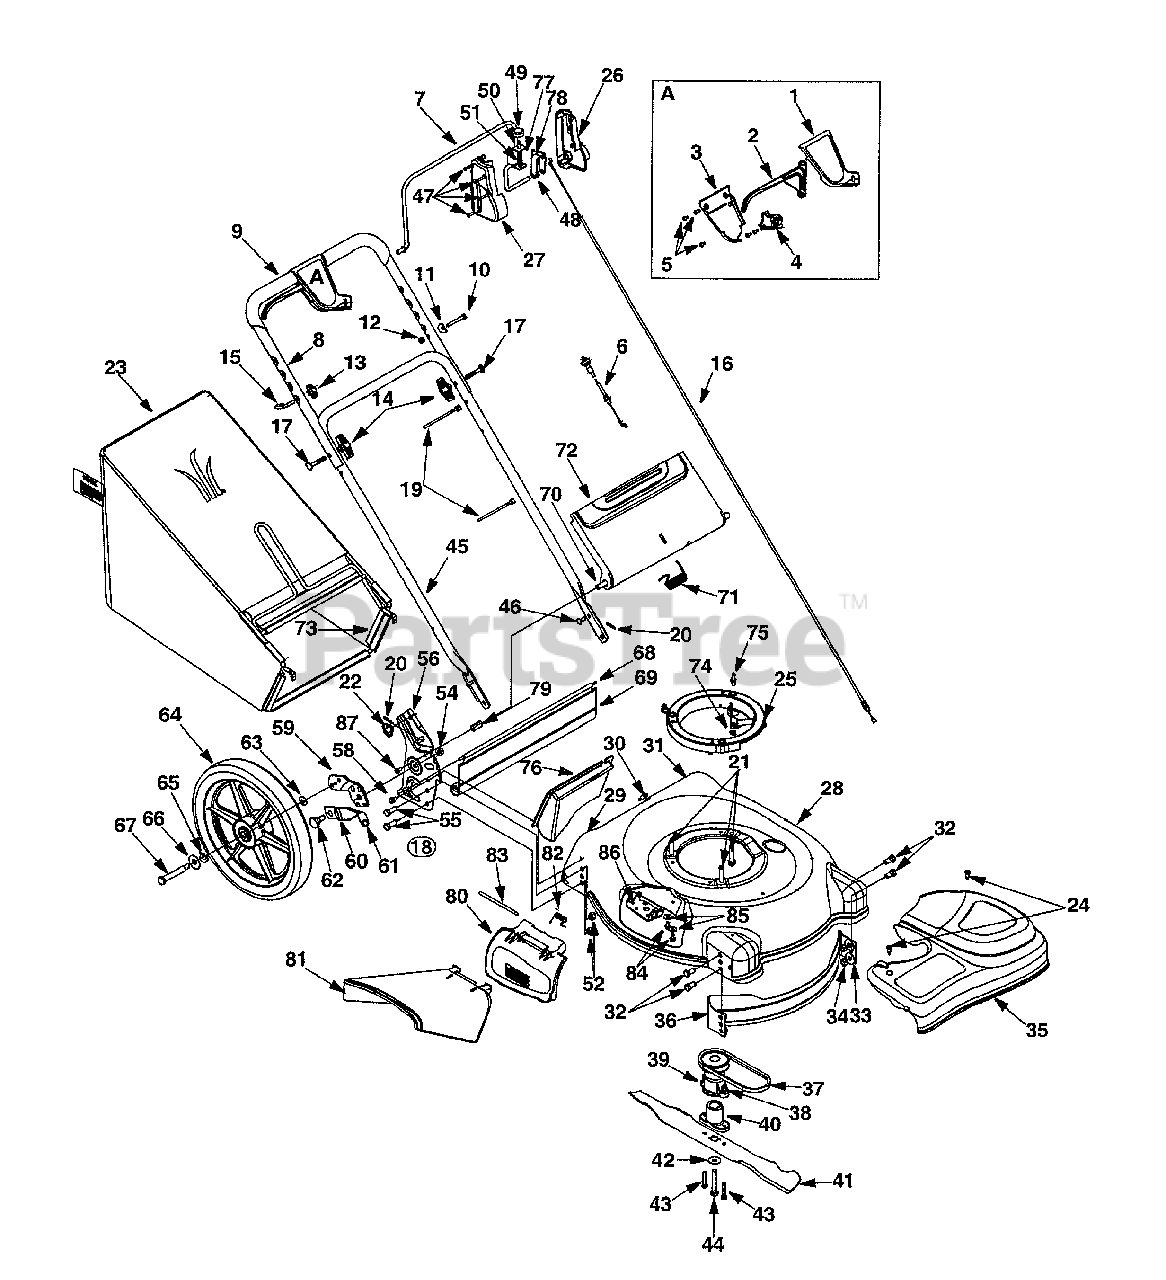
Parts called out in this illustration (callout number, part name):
1	Upper Drive Cover
2	Drive Lever
3	Lower Drive Cover
4	Mounting Cap
5	Screw # 10-16 x .75
6	Drive Cable
10	Hex Hd. Cap Screw 1/4-20
11	Saddle Washer
12	Hex Lock Nut 1/4-20
13	Handle Knob
14	Handle Knob
15	Eye Bolt
16	Control Cable, 58.25"
17	Carriage Bolt 5/16-18 x 2.0
18	RH Bracket Ass'y
19	Cable Tie
20	Cotter Pin
21	Self-Tapping Screw
22	Wing Knob
23	Grass Bag
24	Shoulder Screw
25	Engine Spacer
26	Control Cover LH
27	Control Cover RH
30	Screw AB: 1/4-14: .625
32	Hex Screw 3/8-16 x .75
33	Bell Washer .39 x 1.13 x .062
34	Hex Nut 3/8-16
35	Transmission Cover
38	Hex Nut 1/4-20
39	Drive Pulley
40	Blade Adapter
41	21" Mulching Blade
42	Flat Washer .516 x 1.5 x. 134
43	Hex Screw 1/4-20 x 1.50
44	Hex Screw 3/8-24 x 2.50
46	Carriage Bolt, 1/4-20 x .75"
47	Hi-low Screw
48	Lever
49	Button
51	Compression Spring
52	Hex Nut 3/8-16
54	Hex Flange Lock Nut 3/8-16
55	Hex Scr. w/Washer 1/4-20
58	Hex Screw TT 1/4-14
59	RH Pivot Bar
60	Height Adj. Lever
61	Foam Grip
62	Shoulder Scr .500 Dia. x .434
63	Washer .401 x .870 x .063
64	Wheel, 14 x 2
65	Spring Washer .50 I.D. x 1.0 O.D.
66	Flat Washer .510 x 1.373 x .04
67	Shoulder Screw
68	Wire
69	Rear Trailing Shield
70	Pivot Rod
71	Torsion Spring
74	Hex Nut
75	Screw
76	Plastic Mulching Baffle
77	Retaining Ring
78	Torsion Spring
79	Spacer
80	Mulching Plug (Hinged)
81	Chute Deflector
82	Torsion Spring
83	Hinge Pin
84	Tapp Scr. 1/4-20 x .500
85	Bell Washer .265 x .75 x .062
